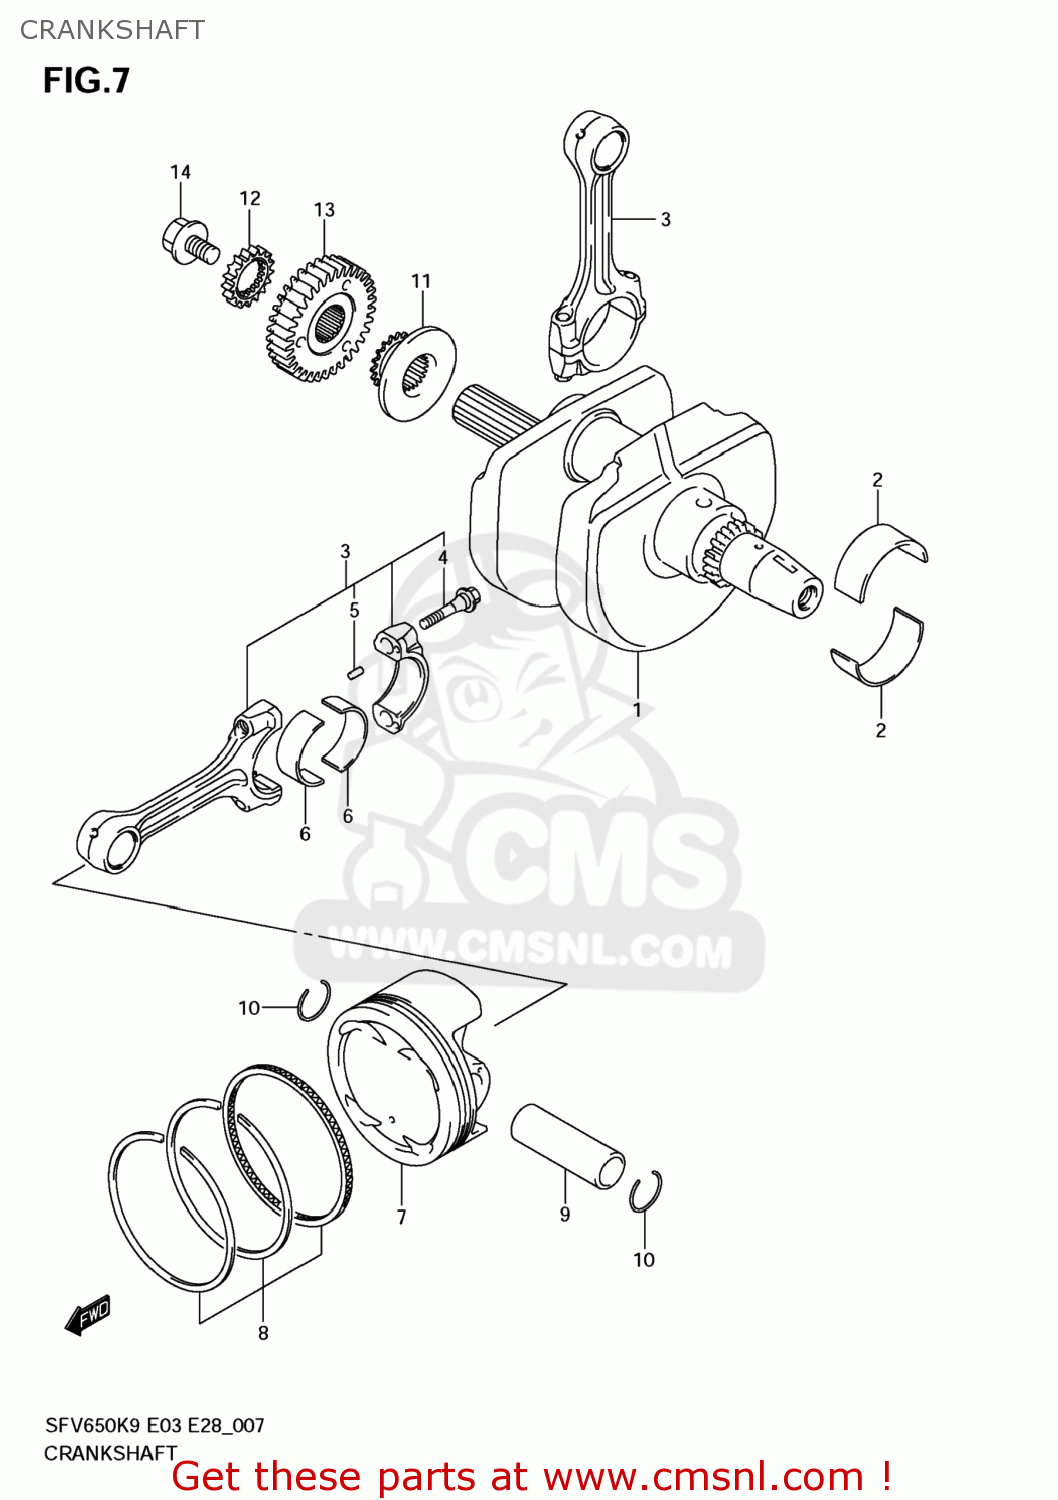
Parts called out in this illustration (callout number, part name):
1	CRANKSHAFT COM
2	BEARING,CRANKSHAFT
3	CONNECTING ROD ASSY
4	BOLT,CONNECTING ROD
5	PIN
6	BEARING,CRANK PIN
7	PISTON
8	RING SET,PISTON
9	PIN,PISTON
10	CIRCLIP,PISTON PIN
11	SPROCKET,CAM CHAIN DRIVE
12	GEAR,WATER PUMP DRIVE
13	GEAR ASSY,PRIMARY DRIVE
14	BOLT(10X19)
